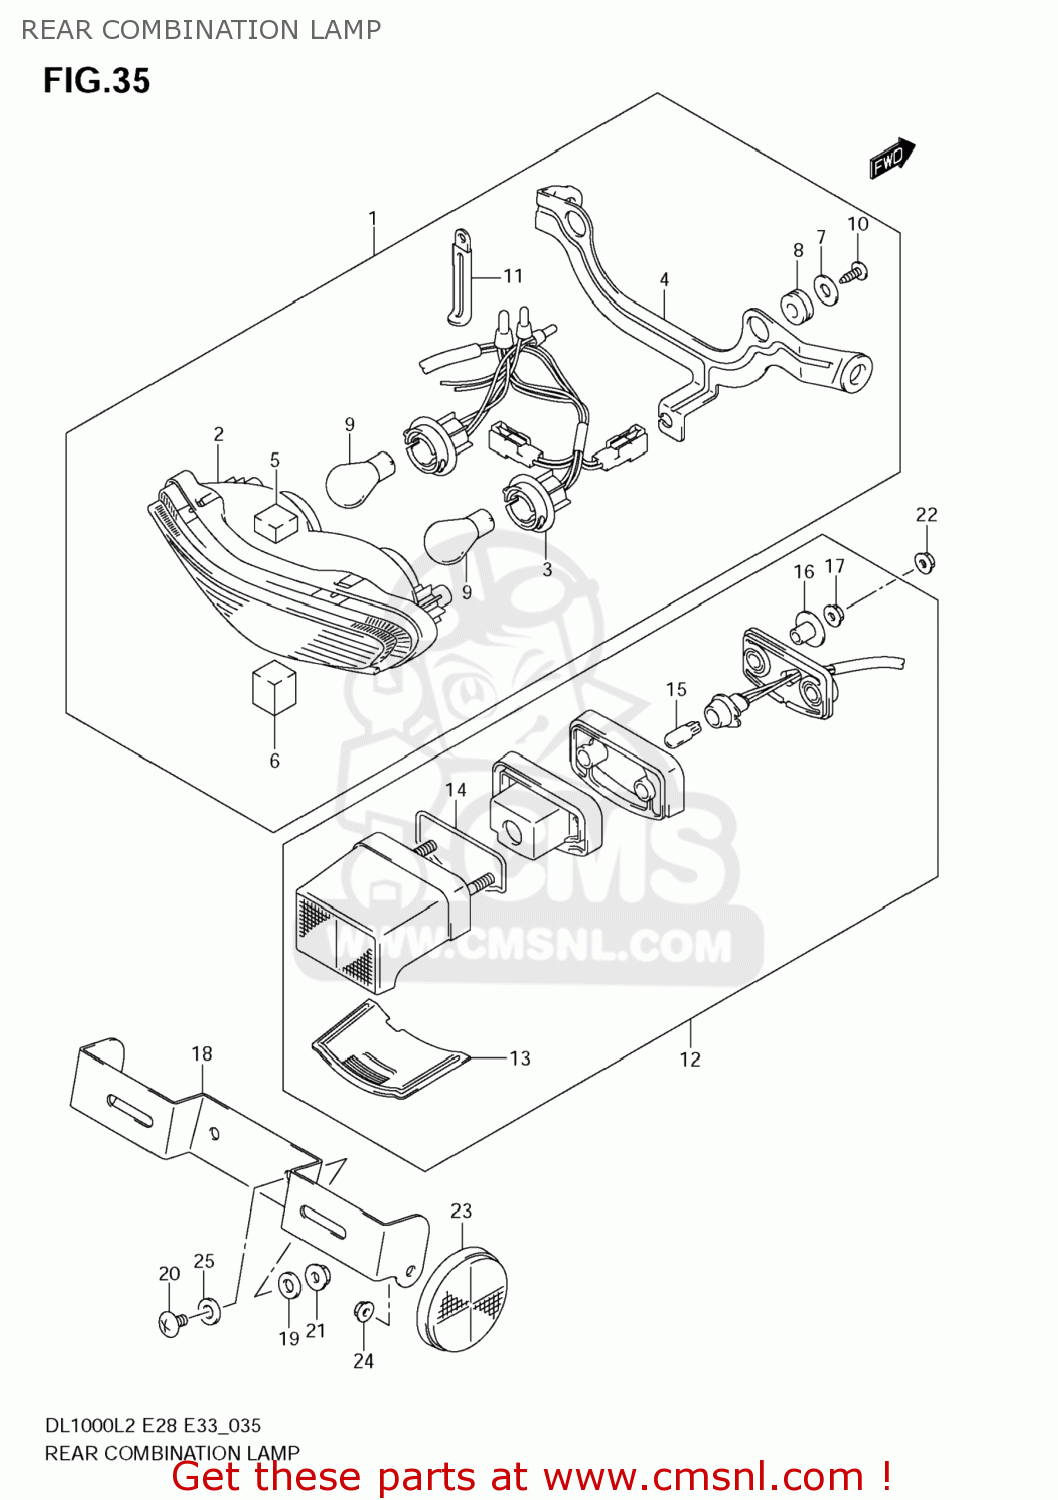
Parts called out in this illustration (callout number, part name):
1	LAMP ASSY,RR COMBINATION
2	UNIT
3	SOCKET & CORD
4	BRACKET
5	CUSHION,UPR(20X20X12)
6	CUSHION,LWR(20X20X25)
7	WASHER(5.5X20X1.2)
8	CUSHION
9	BULB(12V21/5W)
10	SCREW
11	CLAMP(L:45)
12	LAMP ASSY,LICENSE
13	LENS
14	GASKET (NAS)
15	BULB(12V5W)
16	SPACER
17	NUT
18	BRACKET,LICENSE PLATE
19	WASHER(6.5X15X1.6)
20	SCREW
21	NUT
22	NUT
23	REFLECTOR ASSY,RR SIDE
24	NUT
25	WASHER
